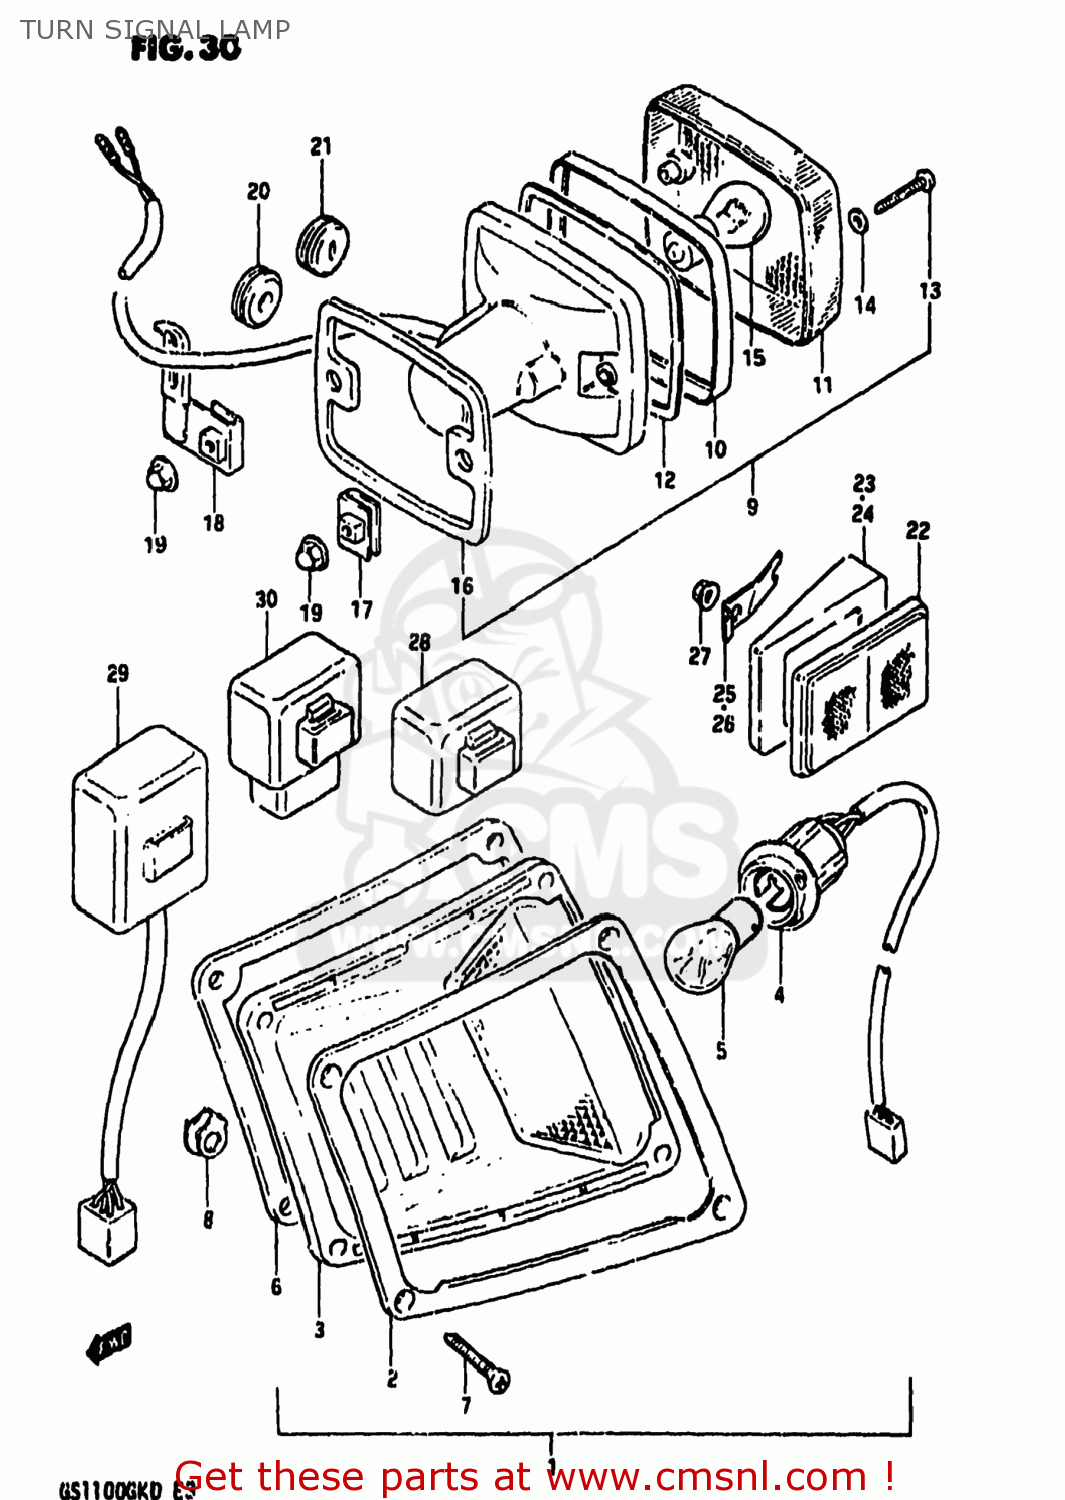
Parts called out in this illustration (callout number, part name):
1	LAMP ASSEMBLY,FRONT TURN SIGNAL
2	RIM,FRONT TURN SIGNAL LAMP
3	COVER,COWLING
4	SOCKET & CORD
5	BULB(12V23W)
6	GASKET,TURN SIGNAL LAMP
7	SCREW,TURN SIGNAL LAMP
8	PLATE
9	LAMP ASSEMBLY,REAR TURN SIGNAL
10	RIM
11	LENS,TURN SIGNAL
12	GASKET (NAS)
13	BOLT
14	GASKET (NAS)
15	BULB(12V23W,STANLEY,A4577A)
16	GASKET
17	PLATE,RR TURN SIGNAL
18	CUSHION
19	NUT 4MM
20	GROMMET
21	GROMMET,TURN SIGNAL LAMP
22	REFLEX REFLECTOR,RR
23	SPACER
24	SPACER
25	WASHER,RIGHT
26	WASHER,REFLECTOR LH
27	NUT
28	RELAY ASSY,TURNSIGNAL
29	UNIT,TURN SIGNAL CONTROL
30	UNIT,TURN SIGNAL CONTROL
